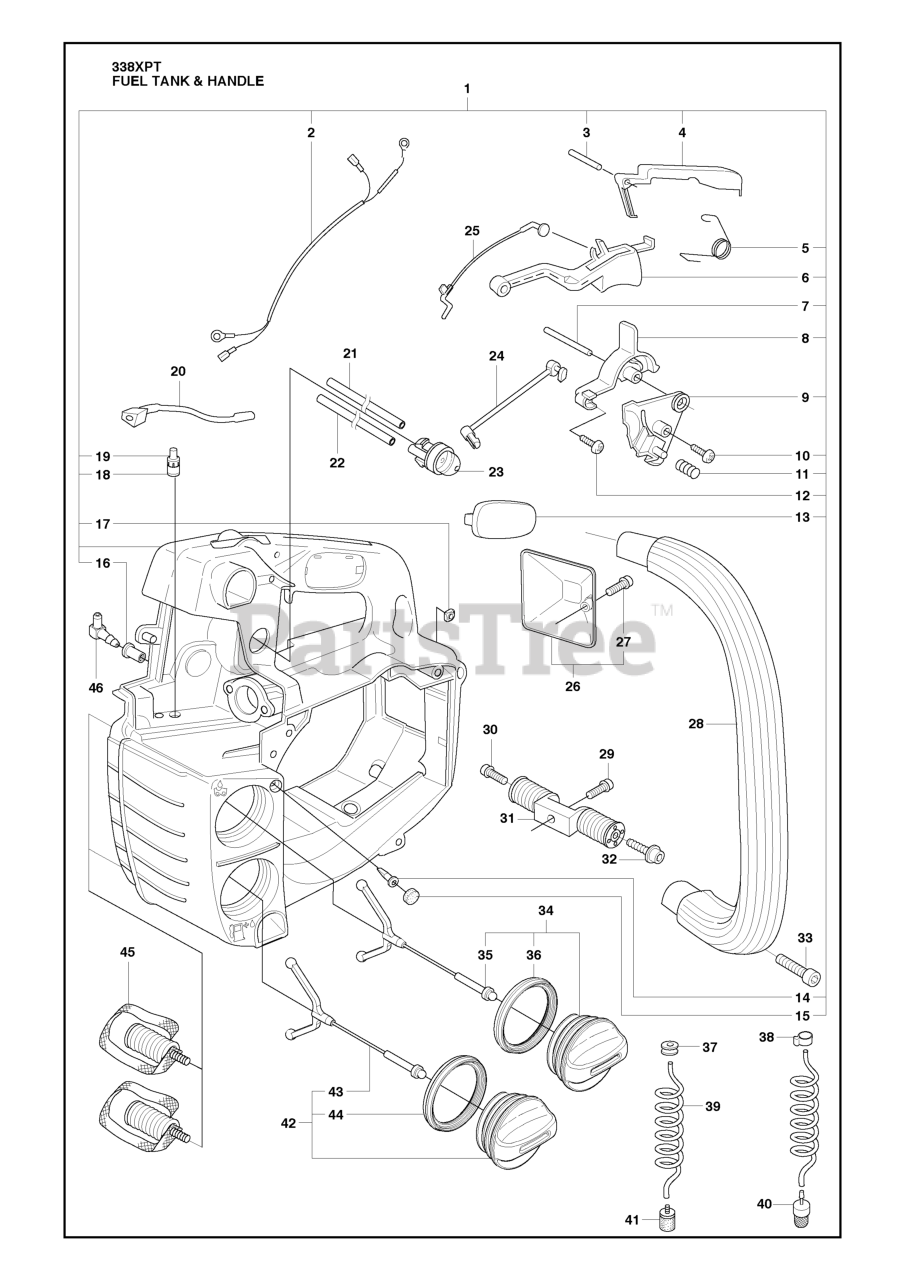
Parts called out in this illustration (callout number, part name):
2	CABLE ASSY
3	PIN 3X25
4	THROTTLE LOCK
8	SWITCH, START/STOP & CHOKE
13	HANDLE INSERT
14	VALVE-CHECK (DUCKBILL)
18	FUEL TANK VENT
23	AIR PURGE BUBBLE
26	SPARK PLUG COVER
31	VIBRATION ABSORBER
34	TANK CAP
36	SEALING
37	FUEL TANK BUSHING
38	CLAMP
39	FUEL HOSE
40	OIL PLUMMET
41	RP FUEL FILTER
42	TANK CAP LIGHT GRAY
44	SEALING
45	ANTI-VIBE ELEMENT
